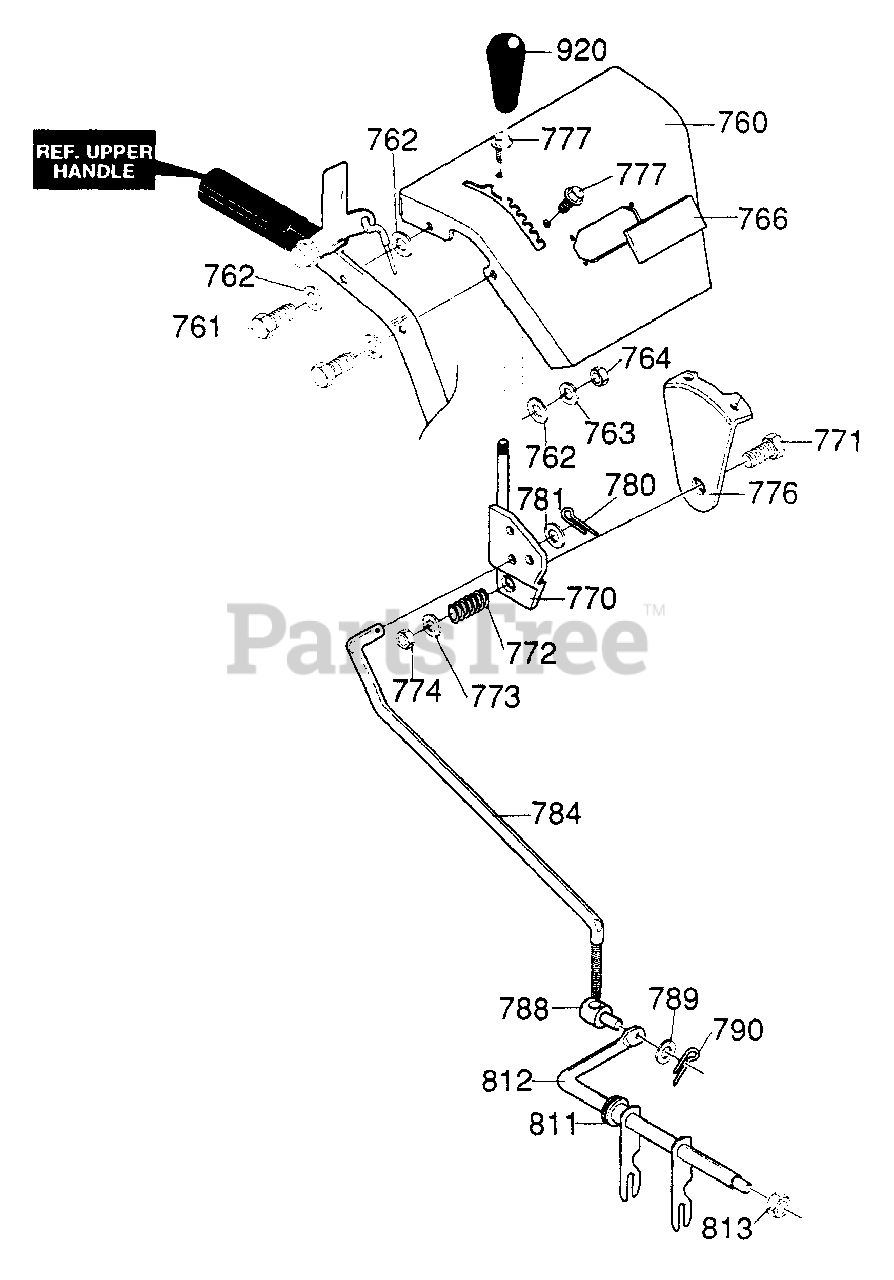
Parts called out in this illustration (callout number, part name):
760	PANEL, CONTROL BS W/LGT
761	SCREW, 5/ 16-18x1.75 HHC
762	FLATWASHER, .344x.69x.065
763	WASHER, HVSPTLK.328x.60x.09
764	NUT, 5/16-18 REGHEX
766	PLATE, PANEL
770	HANDLE, ASSY SPEED CONTROL
771	SCREW, 3/8-16x2.00
773	FLATWASHER, .406x.81 x.065
774	NUT, 3/8-16 HEXNYL
776	BRACKET, SPEED CONTROL
777	SCREW, 5/ 16-18x.75 WAHHTAP
780	PIN, COTTER.090 DIAx.75LG
781	FLATWASHER, .344x.69x.065
784	ROD, SPEED CONTROL
788	NUT, TRUNION 5/16-24
789	FLATWASHER, .344x.69x.065
790	PIN, COTTER.090 DIAx.75 LONG
811	BEARING, FL .500 IDx.88 ODx.31
812	ROD, ASM SPEED CONSOLE
813	NUT, 3/8-16 REGHXCTRLK
920	KNOB. 3/8-16x.75
